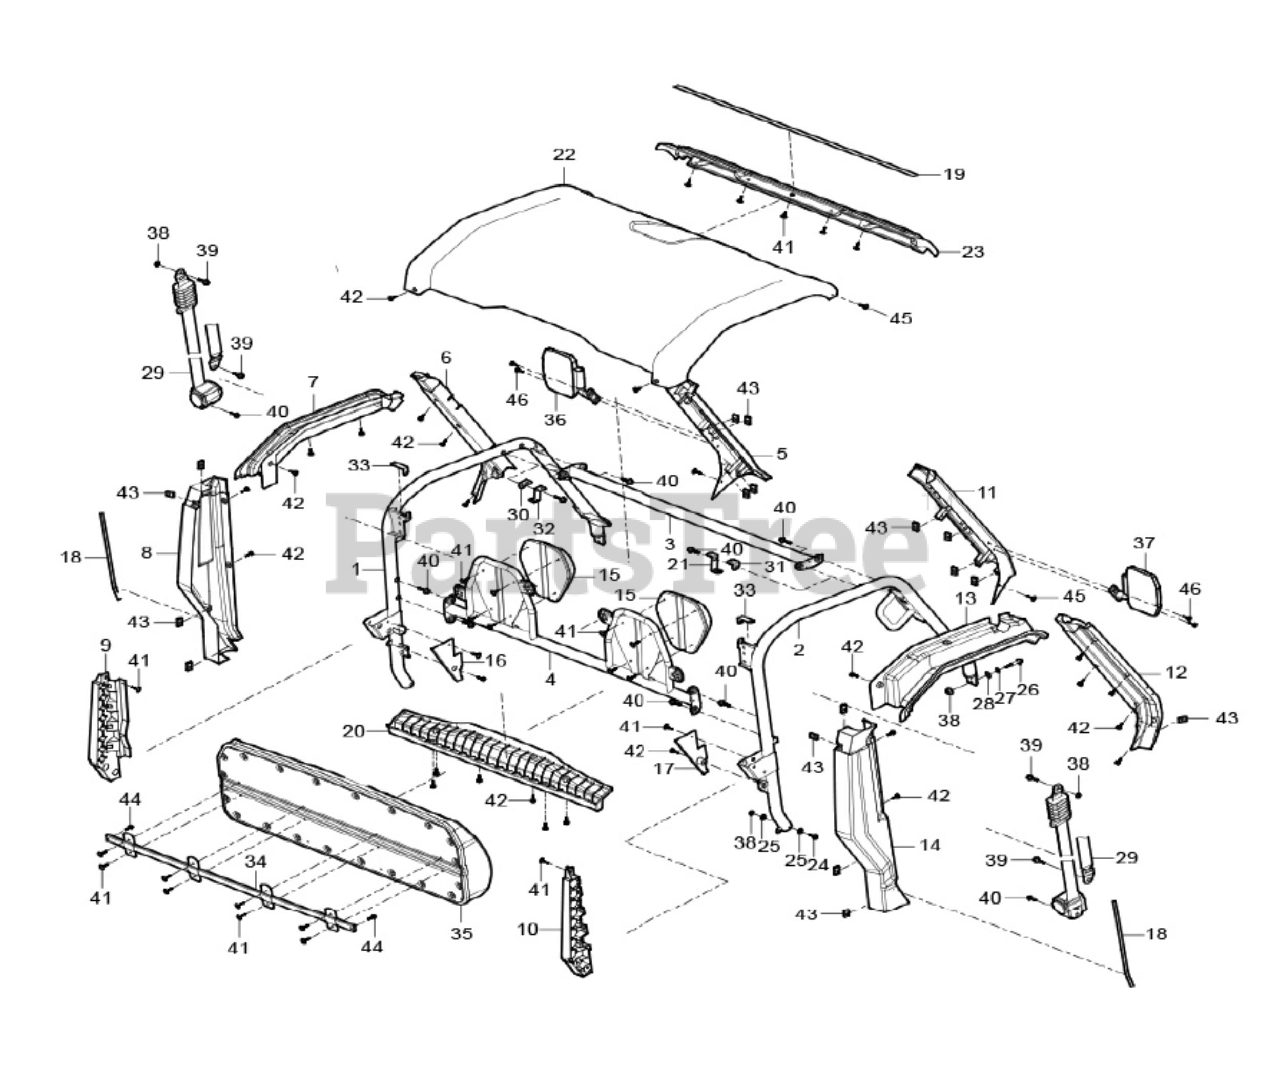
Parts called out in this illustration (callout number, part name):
1	LEFT SUPPORT FRAME KIT
2	RIGHT SUPPORT FRAME KIT
3	FRONT TOP FRAME KIT
4	REAR TOP FRAME KIT
5	A POST TOP COVER - LEFT
6	A POST LOW COVER - LEFT
7	TOP - LEFT PROTECTOR COVER
8	B POST LEFT COVER
9	B POST - LEFT
10	B POST - RIGHT
11	A POST TOP COVER - RIGHT
12	A POST LOW COVER - RIGHT
13	TOP - RIGHT PROTECTOR COVER
14	B POST RIGHT COVER
15	HEADREST KIT
16	B POST PROTECTOR
17	B POST PROTECTOR
18	Door rubber seal IV
19	ROOF DAMPING BAR
20	ROOF GUARD
21	Strap rainshed plated V
22	ROOF
23	BRACKET - LIGHT KIT
24	HEXAGON NUT M10X1.25X65
25	CURVED WASHER
26	BOLT HEXAGON FLANGE HEAD M10X1.25-50
27	SPRING WASHER 10
29	SEAT BELT BUCKLE ASSEMBLY
30	BRACKET PLATED ?
31	BRACKET PLATED II
32	BRACKET PLATED III
33	BRACKET PLATED IV
34	BRACKET - BACKREST PLATED KIT
35	BACKREST KIT
36	REARVIEW MIRROR KIT - LEFT
37	FRONT TOP FRAME KIT
38	LOCK NUT M10x1.25
39	BOLT SHOULDER FLANGE M10x14x9x25
40	Hexagon Flange bolt M10x1.25x20
41	Cross Large Plate Head Screw M6x16
42	Socket Hex Flat Head Bolt M6x16
43	CLAMP NUT M6x6
44	Speaker Case
45	HEXAGON SOCKET HEAD CAP SCREWS M6X16
46	HEXAGON SOCKET HEAD CAP SCREWS M8X25
